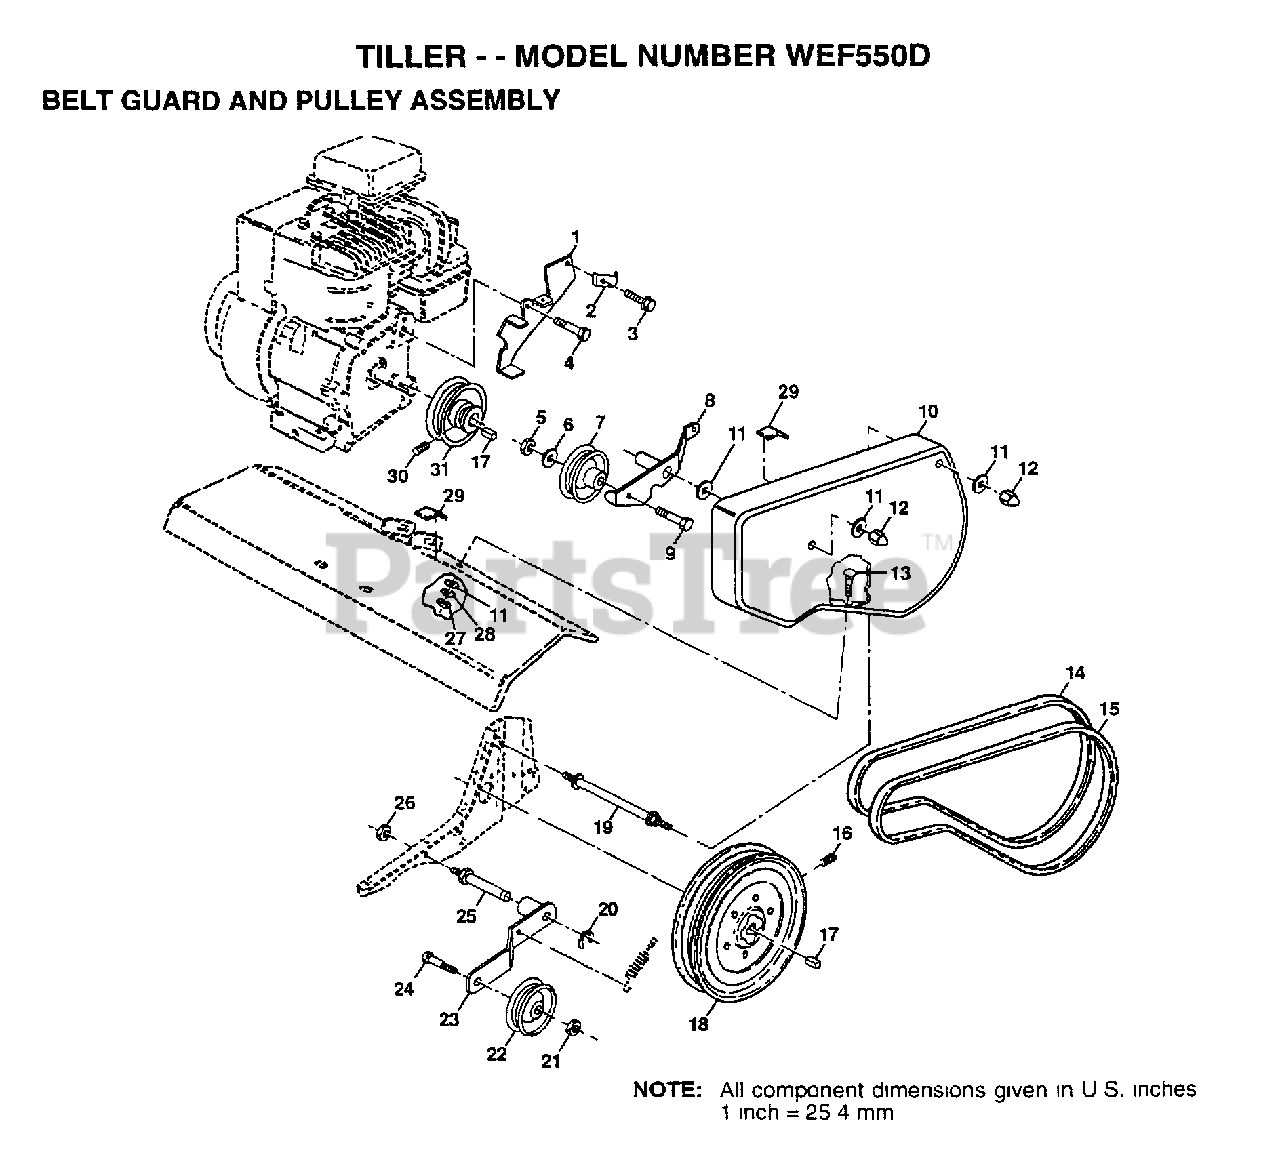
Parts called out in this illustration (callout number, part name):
2	CONDIUT CLIP T
5	NUT.HEX.3/8-16UNC
6	WASHER
7	PULLEY W/SPACER
8	ARM.ASM.REV.IDLER
10	GUARD BELT
11	WASHER
12	NUT-CAP TI
13	BOLT T
14	BELT-V
16	SET SCREW
17	KEY T
19	BOLT TI
20	KLIP RING TI
21	NUT
23	IDLER ARM TI
25	SHAFT IDLER TI
26	JAM NUT TI
28	LOCKWASHER
29	PAD IDLER TI
30	SET SCREW
31	ENGINE PULLEY TI
